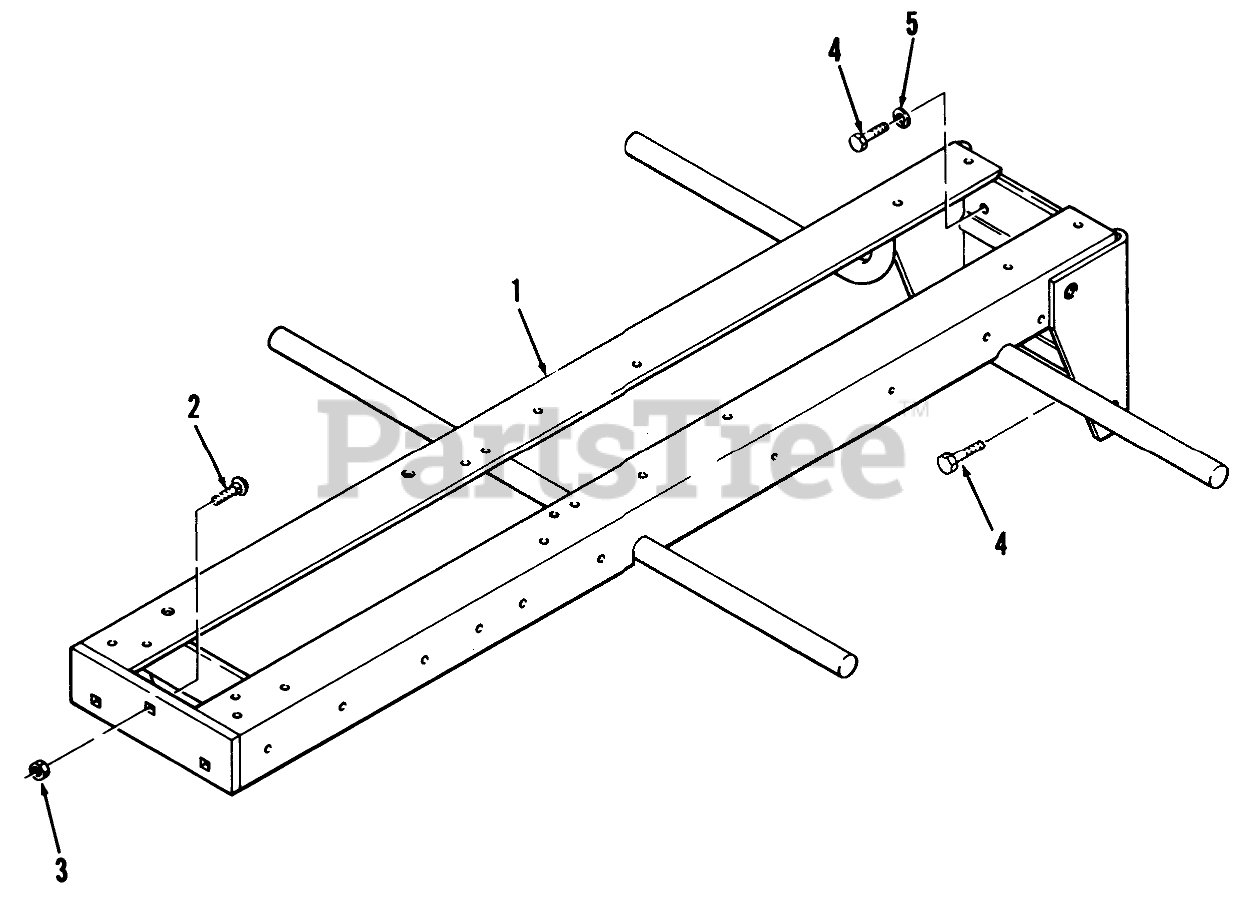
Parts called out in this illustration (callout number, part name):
1	WLDMT-FRAME R
2	Bolt
3	NUT-LOCK, NI
4	SCREW-HH
5	LOCKWASHER
